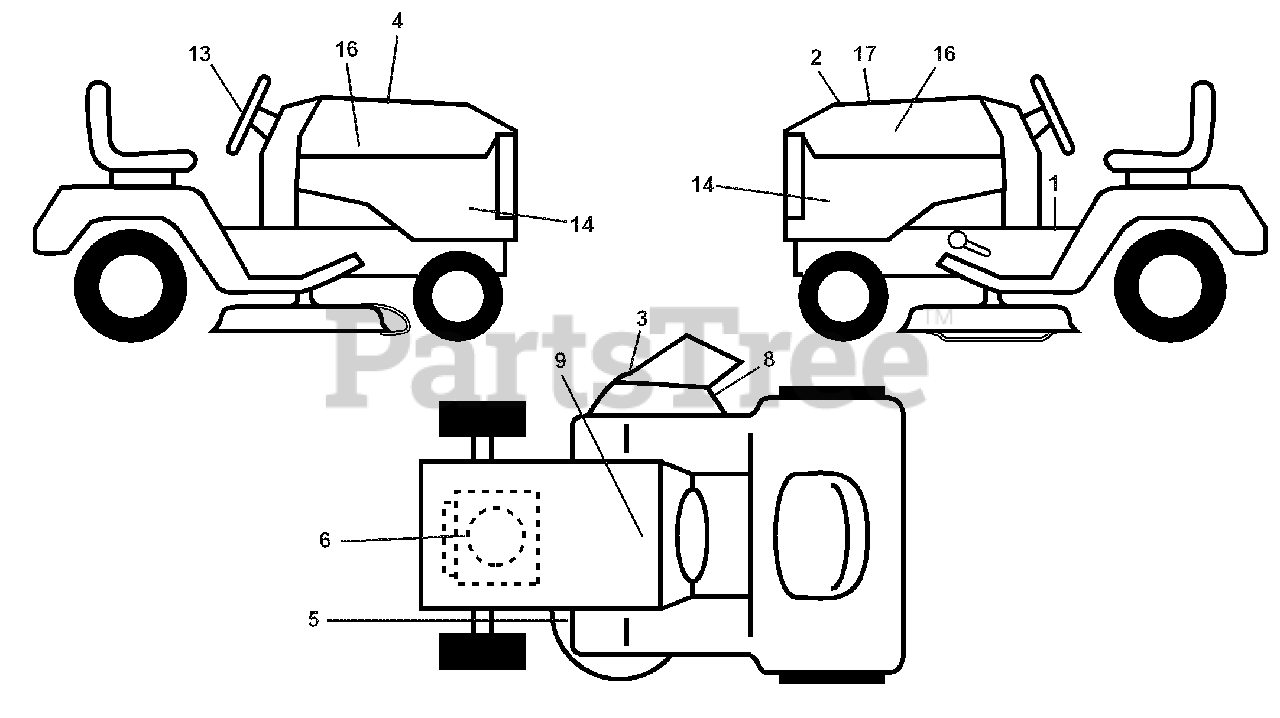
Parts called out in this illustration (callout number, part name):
1	Decal, Operator's
2	Decal, Hood Insert
3	Decal, Warning
4	Decal, Hood Cust Resp
5	Decal, Caution
6	Decal, Eng. HP
8	Decal, Mower Sch.
9	Decal, Battery Dnge/Poi
13	Decal, Steering Whl
14	Decal, Panel Side
16	Decal, Hood Logo
17	Decal, Replacement
